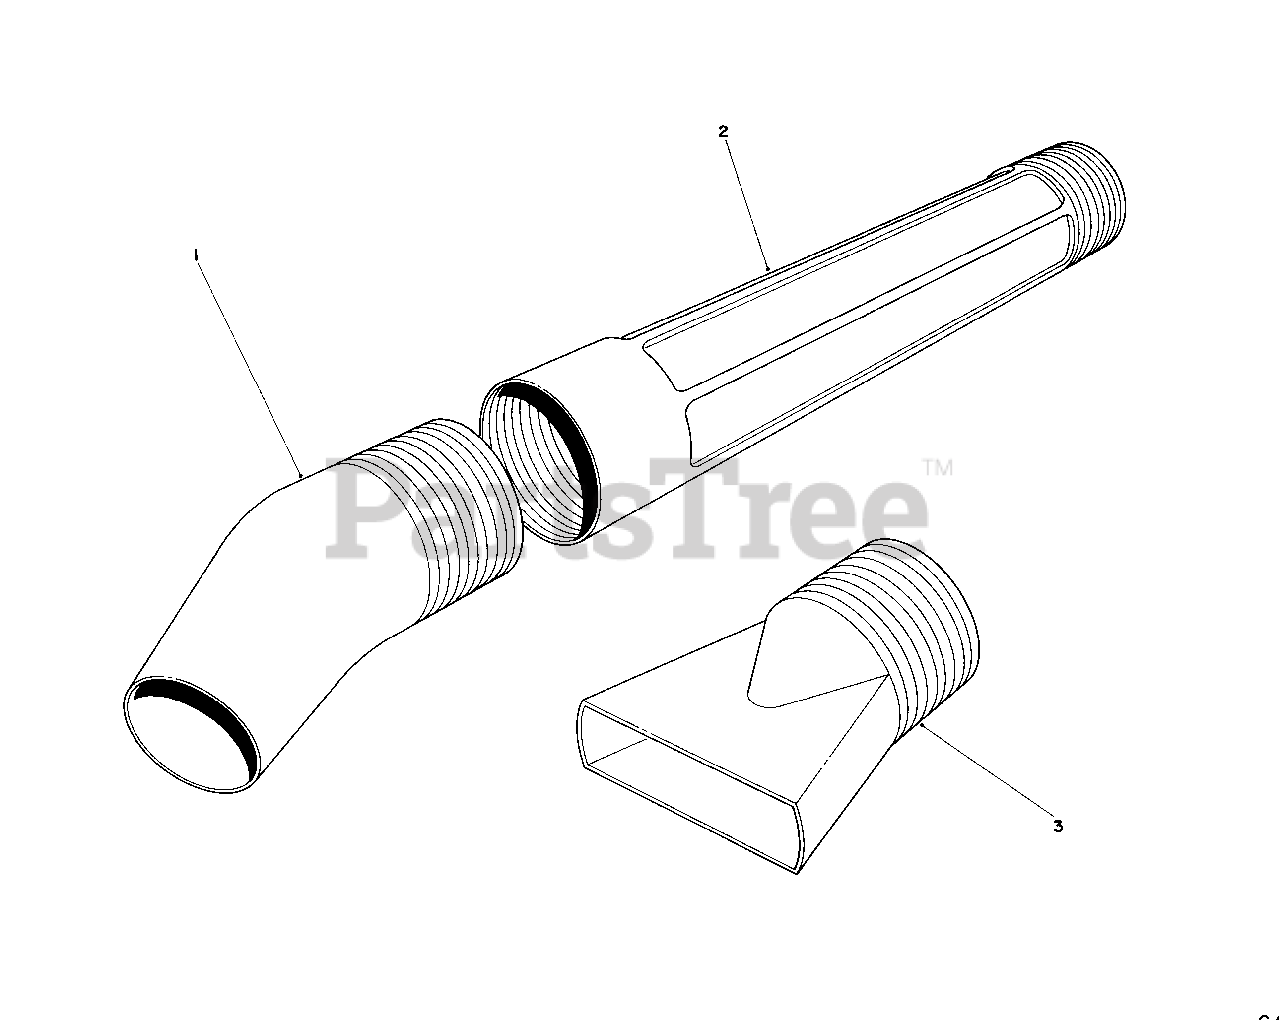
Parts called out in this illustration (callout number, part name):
1	Nozzle-Concentrating
2	Tube-Blower
3	Nozzle-Diffusing (Model No. 51545)
